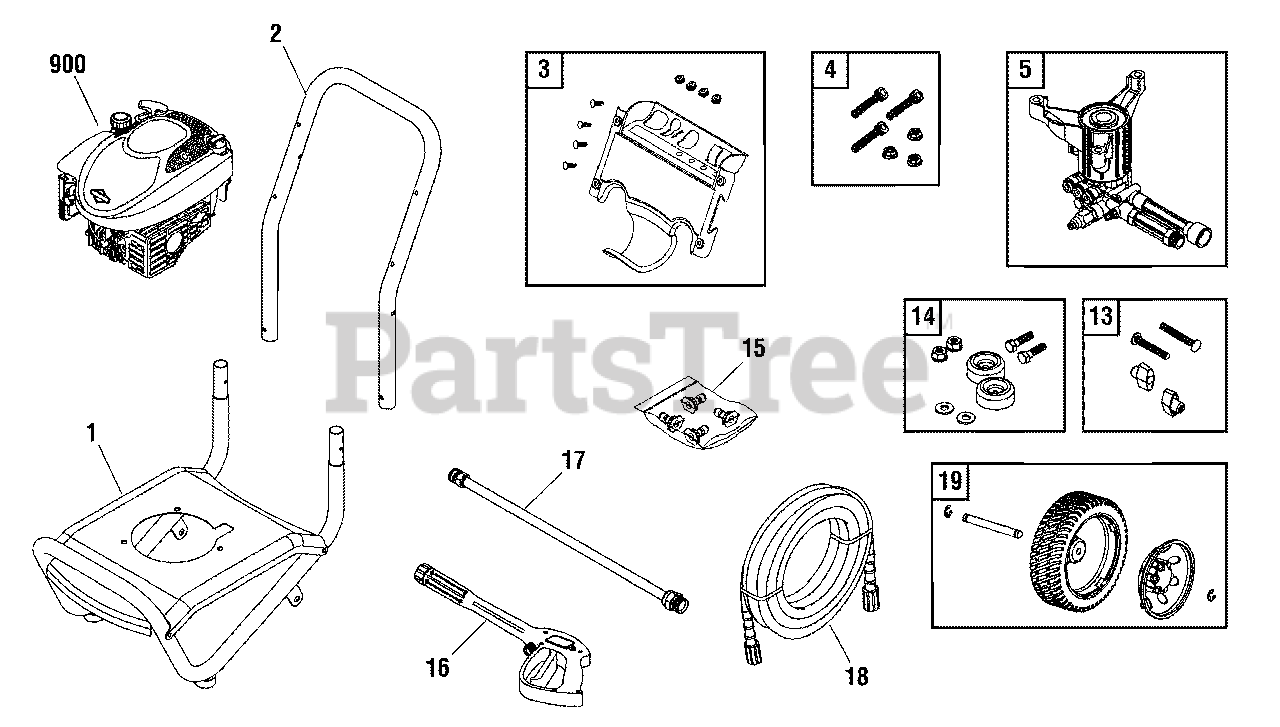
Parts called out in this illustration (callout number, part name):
1	BASE, w/Vibe Mounts
2	HANDLE
3	ASSY, Billboard w/Decal & Clips
4	KIT, Hardware, Pump Mounting
5	PUMP
13	KIT, Hardware, Handle
14	KIT, Vibration Mount
16	GUN
17	EXTENSION, QC
900	* ENGINE
